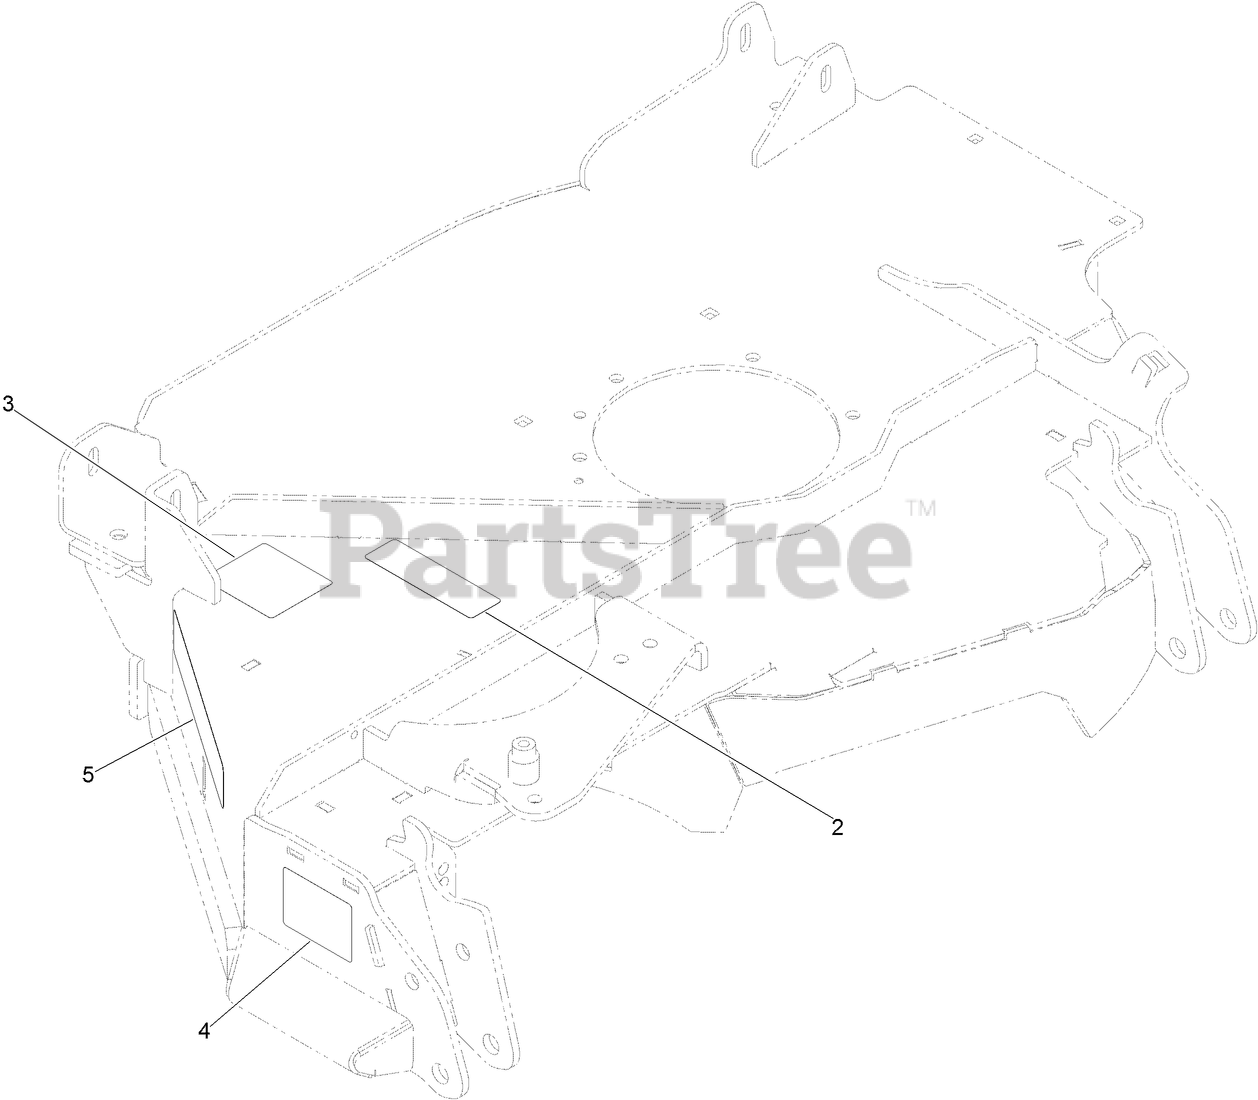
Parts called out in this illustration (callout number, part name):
2	DECAL-COVER, MISSING
3	DECAL-DANGER, THROWN OBJECT
4	DECAL-WARNING, PINCH POINT
